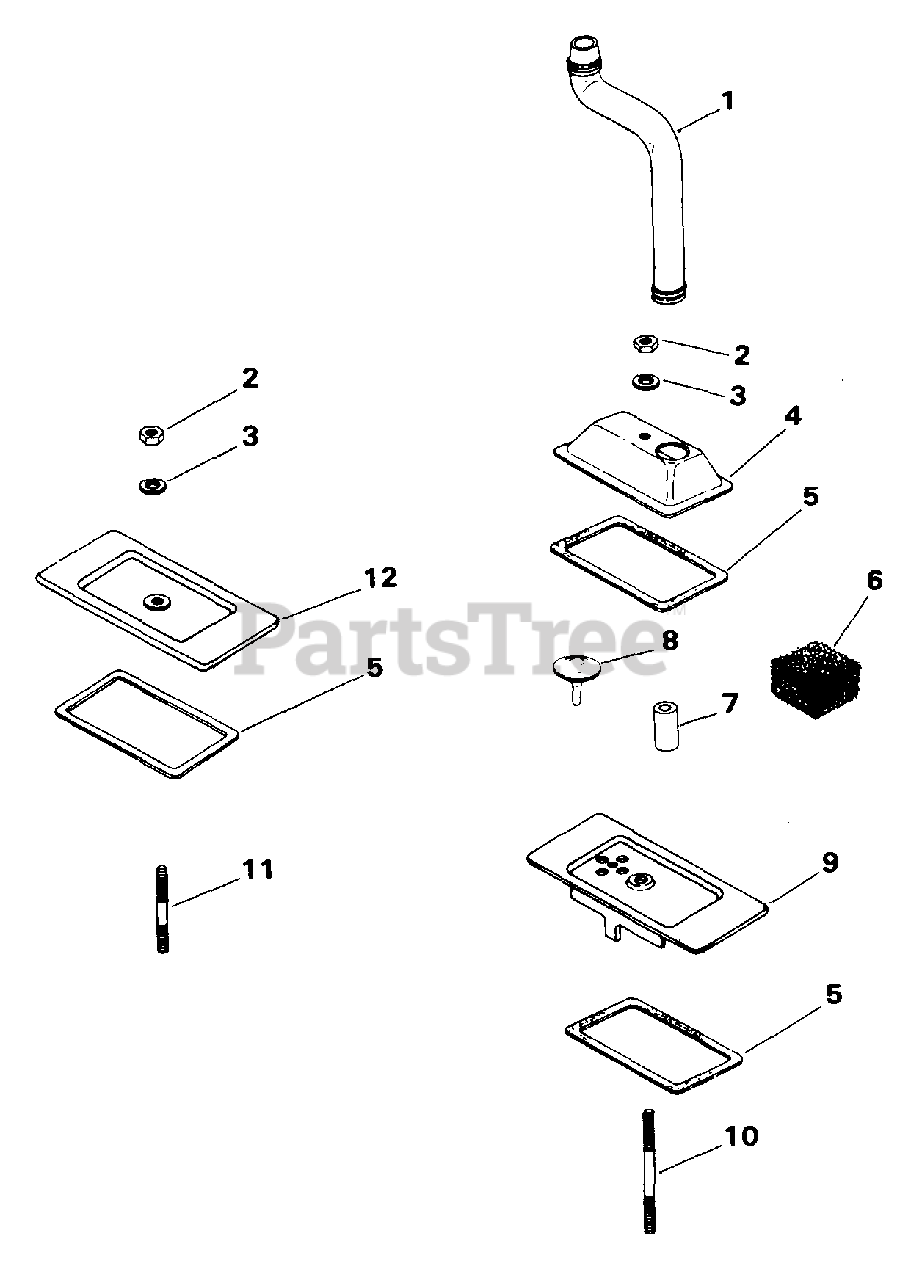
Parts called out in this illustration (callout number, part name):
2	NUT, 1/4-20 GRADE 2 USE 25 100 20-S
6	FILTER, BREATHER
8	VALVE, UMBRELLA - DISCONTINUED
9	BREATHER - USE 52 035 02
10	STUD, 1/4-20x3-1/4" - DISCONTINUED
11	STUD, 1/4-20x2-1/4" USE 25 072 11-S
12	COVER - USE 52 096 55
